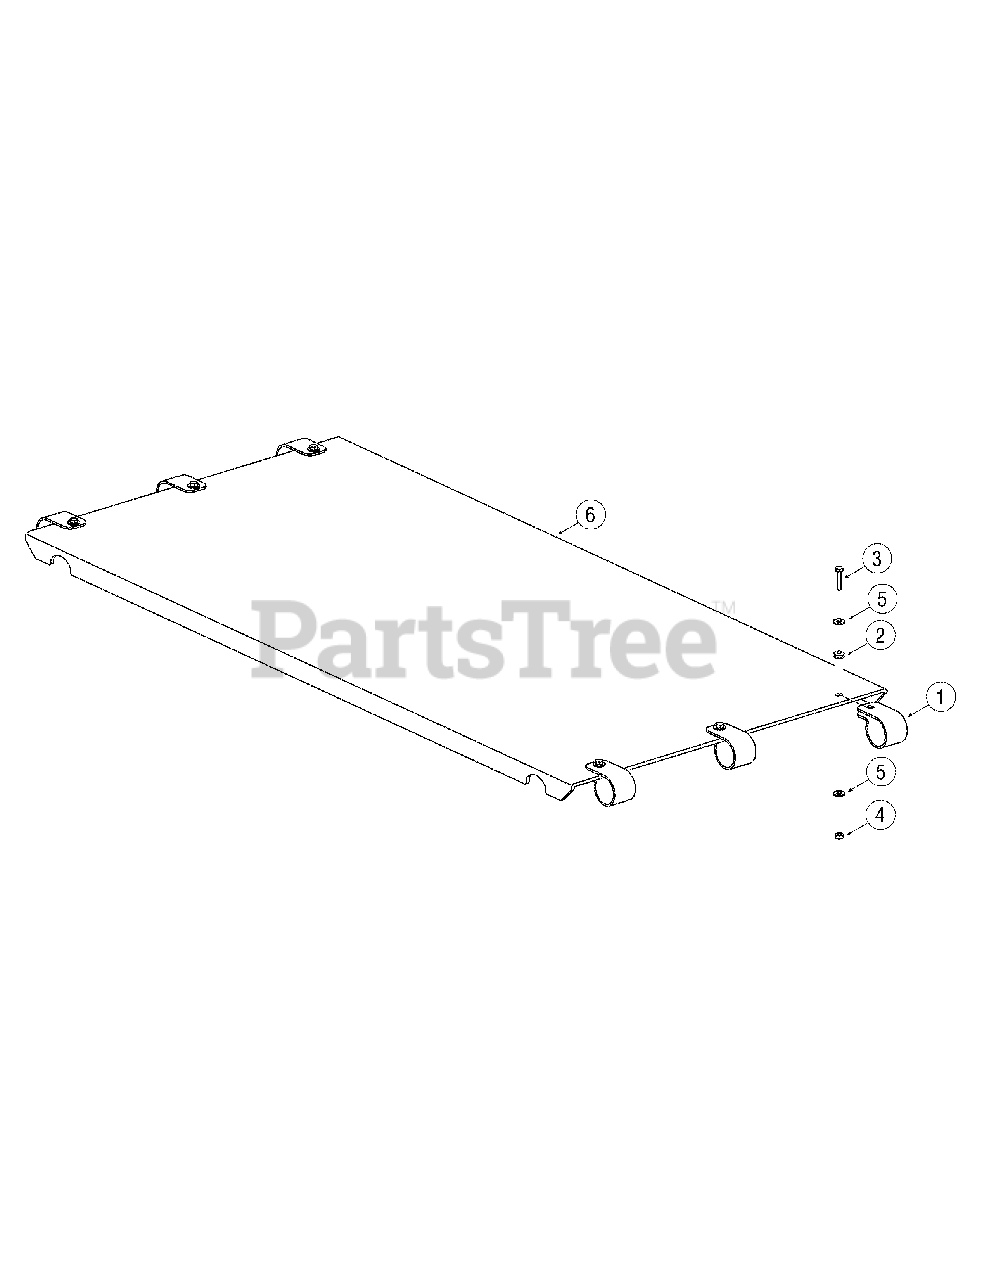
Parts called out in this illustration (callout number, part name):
1	1.75" Windshield Clamp
2	1/4 ID, 5/8 OD Grommett
3	Hhcs, 1/4-20 x 1.00
4	Nut, Hexlk, 1/4-20
5	Wash, flat, .271 x .630 x .065
